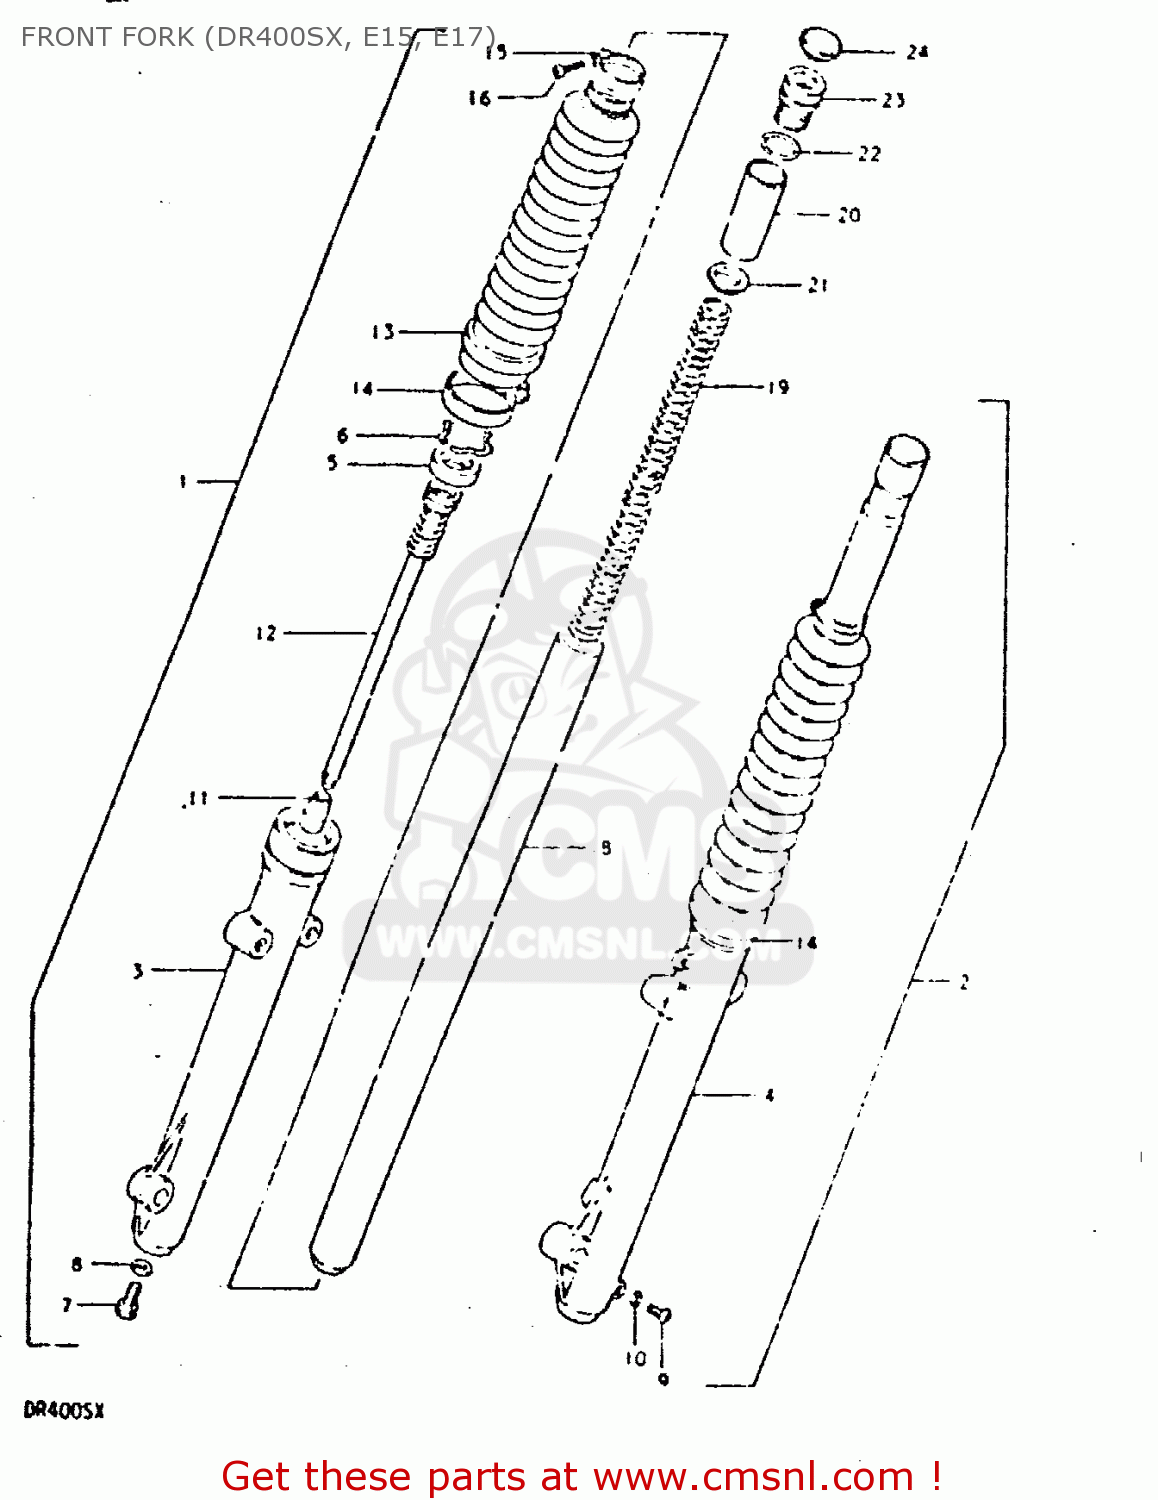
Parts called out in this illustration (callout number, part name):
1	DAMPER ASSY, RH
2	DAMPER ASSY, LH
3	TUBE,OUTER,RIGHT
4	OUTER TUBE, LH
5	OIL SEAL,FRONT FORK
6	7
7	BOLT,FORK CYLINDER(10X25)
8	GASKET (NAS)
9	SCREW
10	GASKET,DRAIN,PLUG (NAS)
11	PIECE,OIL LOCK
12	CYLINDER,FRONT FORK
13	BOOT
14	BAND,FRONT FORK COVER
15	BAND,BOOT
16	SCREW
17	INNER TUBE
18	INNER TUBE, LH
19	SPRING
20	SPACER,SPRING
21	GUIDE,FRONT FORK SPRING C
22	O RING
23	CAP,FORK INNER TUBE
24	CAP,FRONT FORK
